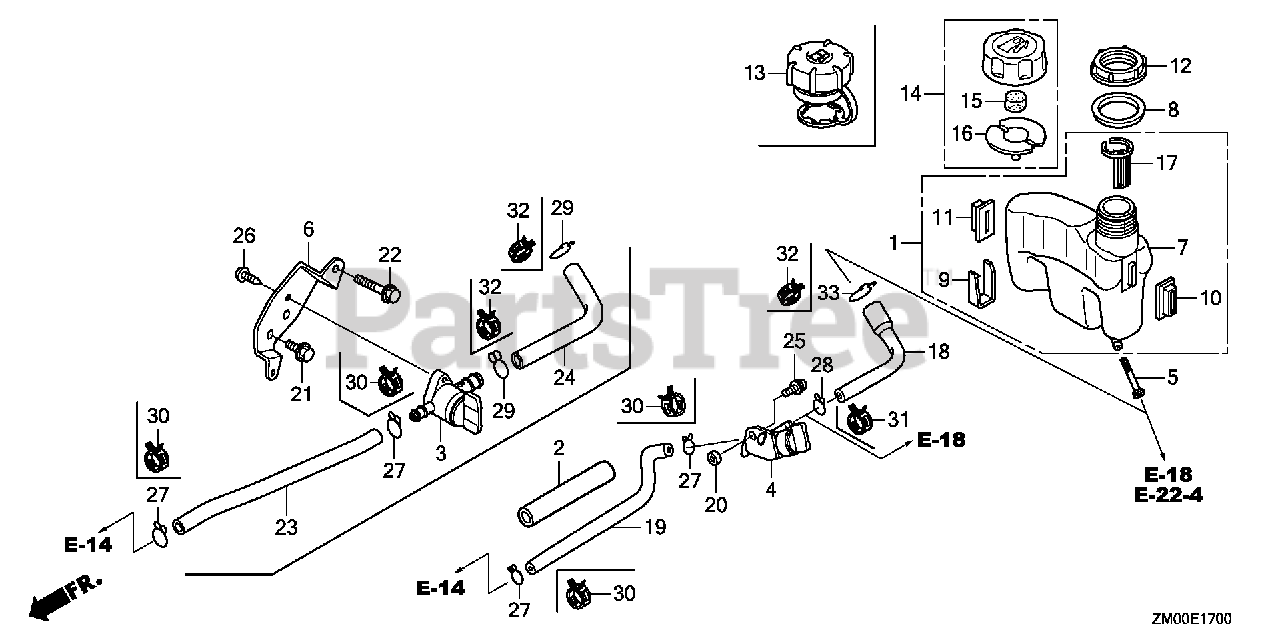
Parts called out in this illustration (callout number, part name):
3	PETCOCK ASSY.
5	FILTER, FUEL
6	STAY, PETCOCK
7	TANK, FUEL
8	SEAL, FUEL FILLER NECK
10	RUBBER A, TANK MOUNTING
11	RUBBER B, TANK MOUNTING
12	NUT, TANK MOUNTING
13	CAP ASSY., FUEL TANK
17	GAUGE, FUEL LEVEL
21	BOLT, FLANGE (6X12) (CT200)
22	BOLT, FLANGE (6X28) (CT200)
23	TUBE, FUEL (4.5X110)
24	TUBE, FUEL (7.3X160)
26	SCREW, TAPPING (5X12) (PO)
27	CLIP, TUBE (C9)
29	CLIP, TUBE (B12.5)
